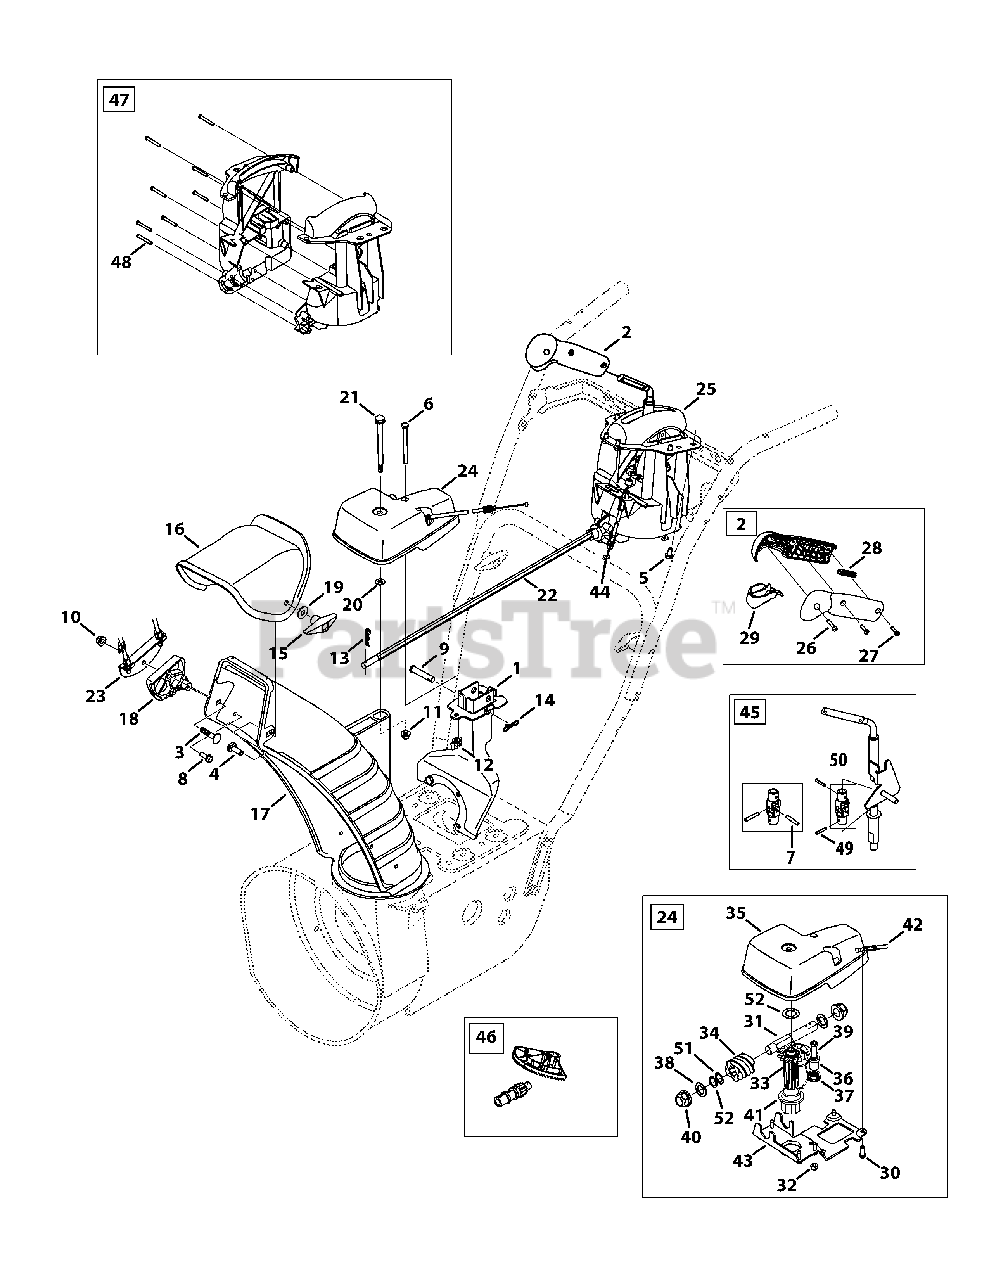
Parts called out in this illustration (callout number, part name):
1	Chute Support Bracket
2	Handle Assembly
3	Bolt, Carriage, 5/16-18 x 1.50
4	Bolt, Carrier, 5/16-18 x 1.00
5	Screw, HL, 1/4-15 x 0.50
6	Hex Head Screw, 1/4-20 x 3.00
7	Pin, Roll
8	Screw, HL, 1/4-15 x 0.750
9	Clevis Pin, 3/8 x 1.87
10	Nut, Flangelock, 5/16-18
11	Nut, Flangelock, 1/4-20
12	Wing Nut, 1/4-20
13	Internal Cotter Pin
14	Bow-Tie Cotter Pin
15	Wing Knob, 5/16-18
16	Chute, Upper
17	Chute, Lower
18	Cable Guide, Chute Tilt
19	Washer, Flat, .349 x .879
20	Washer, Flat, .25 x .630
21	Screw, Shoulder, .312 x 3.5 x 1/4-20
22	Chute Rod, 3/8 Hex
23	Cable Bracket
24	Gearbox Assembly, Chute Rotation
25	Chute Control, 4-Way
26	Screw, #8 x 1.00
27	Screw, 8-32 x .750
28	Joystick Plug
29	Joystick Trigger
30	Screw, 12-16 x .75
32	Hexlock Nut, 1/4-28
33	Gear, 14 T
34	Worm
35	Gear Cover
37	Torsion Spring, .721 ID x .474
38	Washer, Flat, .625 x 1.0 x .067
39	Screw, Shoulder, .340 x .950 x 1/4-28
40	Hex Bearing
41	Flange Bearing
44	4-Way Cable
44	Cable Clip
45	Shift Assembly
46	Gear Set Assembly
47	Handle Housing Assembly
48	Screw, #8-18 x 1.250
50	Block, Asm Joint
51	Shim Washer, .632 x 1.00 x .010
52	Shim Washer, .63 x 1.00 x .020
